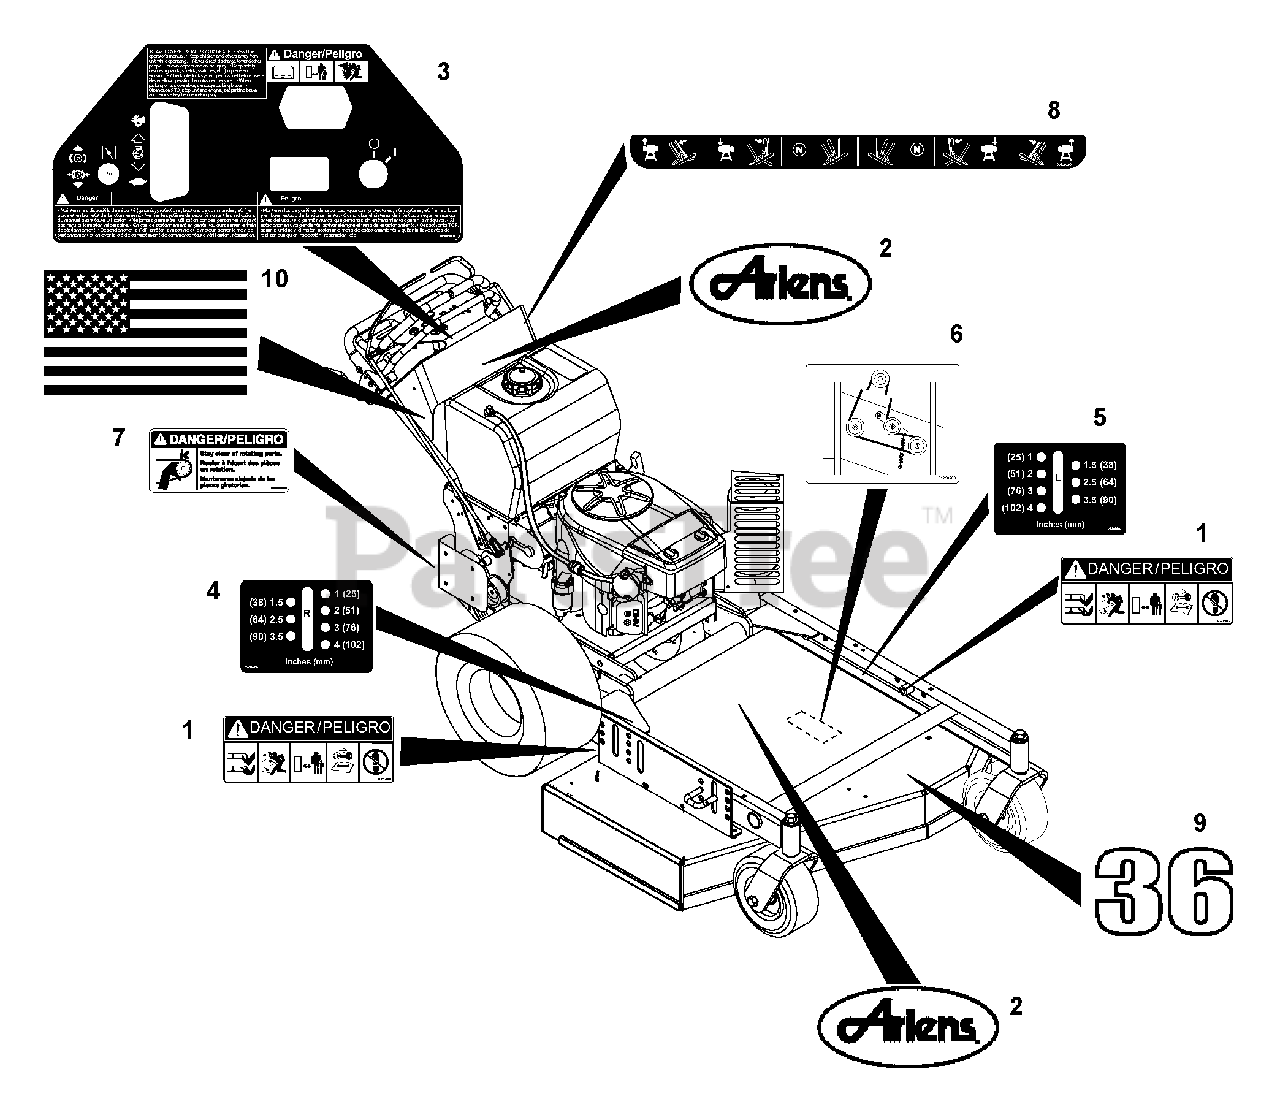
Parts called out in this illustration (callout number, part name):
1	DECAL, MOWER PAN DANGER
2	DECAL, ARIENS
3	DECAL - CONTROL HR15 - ERGO
4	DECAL-HEIGHT OF CUT-FIXED - RH
5	DECAL-HEIGHT OF CUT-FIXED - LH
6	DECAL-BELT DIAGRAM-2 SPINDLE
7	DECAL-DANGER-BELT ROTATING
8	DECAL-STEER LEVERS-HYDRO-ERGO
9	DECAL, 36
10	DECAL, AMERICAN FLAG
